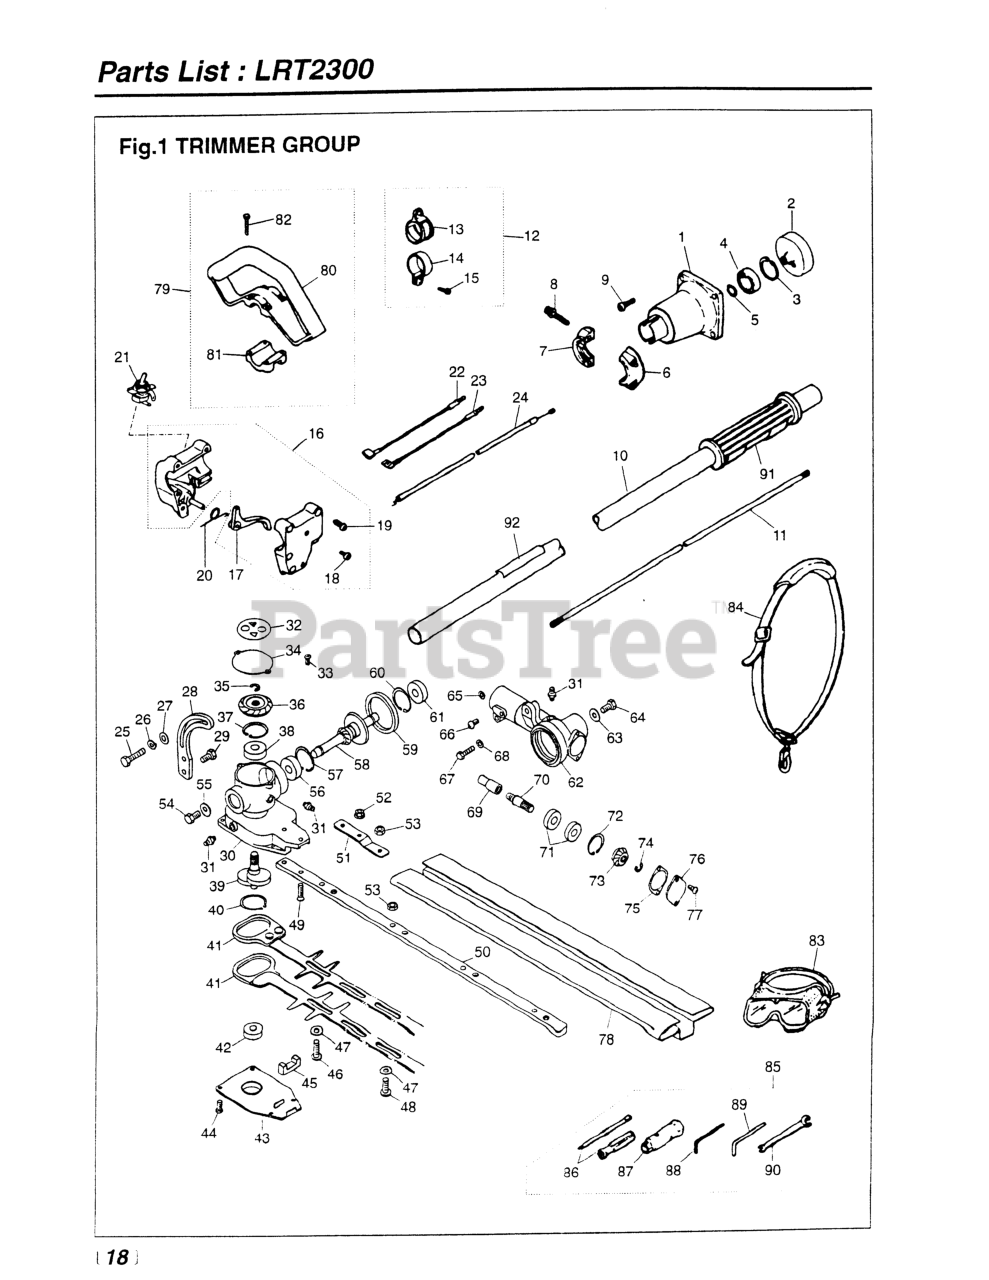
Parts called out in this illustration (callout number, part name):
3	RING, SNAP, M28 x 1.2
4	BEARING
5	RING, SNAP (RPLS 3130-13270)
6	CLAMP, LEFT
7	CLAMP, RIGHT
8	BOLT
9	BOLT, M6 x 20
12	HANGER COMPLETE
13	HANGER
14	CLAMP
15	SCREW, M5 x 25
17	LEVER, THROTTLE
18	SET SCREW, ANTI-ROTATION
19	SCREW
20	SPRING, THROTTLE TRIGGER
21	SWITCH, STOP
22	CORD, RED (LEAD WIRE)
23	CORD, BLACK (LEAD WIRE)
24	CABLE COMP
26	WASHER, M6 X 15
27	WASHER, 6 X 6 X 2.0
28	ADJUSTER, ANGLE (USE-13141)
31	FITTING, GREASE
33	SCREW, M4 X 8
35	RING, SNAP
36	GEAR, BEVEL
37	RING, SNAP, M26 X 1.2
38	BEARING
39	CRANKSHAFT
40	RING, SNAP, M28 X 1.5
42	BEARING
44	BOLT, M4 X 8
45	FELT
47	WASHER (RPLS 3873-11760)
48	SCREW
49	SCREW, M5 X 20
50	PLATE, GUIDE
51	PLATE (RPLS 6780- )
52	NUT, M5
53	NUT, M6
55	WASHER, 6X15X2.0
56	BEARING
57	RING, SNAP, M22 x 1.2
59	O-RING
60	RING, SNAP, M26 X 1.2
61	BEARING
62	CASING
63	WASHER, 6 X 6 X 2.0
65	WASHER
66	SCREW, M5 x 10
67	BOLT, M5 x 25
68	WASHER, M5 x 10
69	JOINT (REPLACES T3078-13810)
70	SHAFT, GEAR
71	BEARING
72	RING, SNAP, M22 x 1.2
73	GEAR, BEVEL
74	RING, SNAP
75	PACKING
76	COVER, STOPPER KIT
77	SCREW, M4 X 8
78	COVER, BLADE
79	HANDLE ASSEMBLY
80	HANDLE
81	CLAMP
82	SCREW, M5 x 35
83	GOGGLE
84	SHOULDER STRAP ASSY
85	TOOL SET
86	SCREWDRIVER
88	WRENCH (TOOL)
89	BAR
90	SPANNER, 8 X 10 (RPLS 2540- )
92	DECAL
